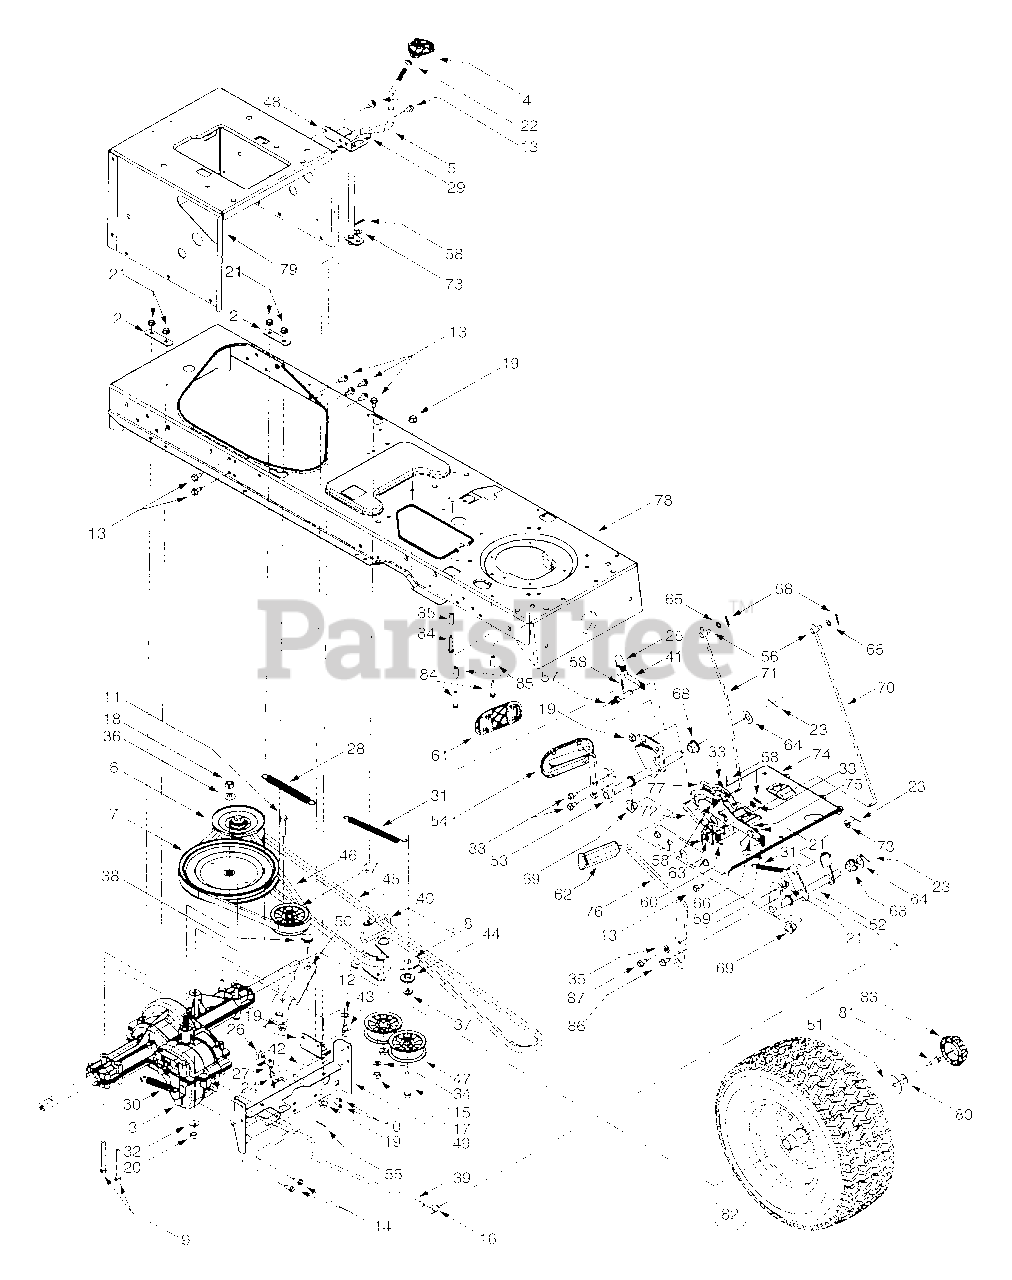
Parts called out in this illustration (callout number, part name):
3	Single-speed Transmission Assembly
4	Shifter Knob
5	Shift Lever
6	Variable-speed Pulley Assembly
7	Transmission Pulley, 8.5 x .5-36
8	Double-idler Bracket
9	Hex Cap Screw, 5/16-18 x 2.75
10	Self-tapping Screw, #8-18 x .5
11	Hex Cap Screw, 3/8-16 x 1.75
12	Flat Washer, .51 x 1.0 x .060
13	Self-tapping Screw, 5/16-18 x .625
14	Self-tapping Screw, 1/4-20 x .75
15	Hex Cap Screw, 3/8-16 x 2.25
16	Ferrule, 5/16-18
17	Hex Nut, 3/8-24
18	Hex Nut, 7/16-20
19	Flange Lock Nut, 3/8-16
20	Hex Nut, 3/8-16
21	Flange Lock Nut, 5/16-18
22	Jam Nut, 3/8-16
23	Cotter Pin
24	Internal Cotter Pin
25	Ball Joint
26	Short Spring Switch
27	Insulator Nut Plate
28	Extension Spring, .62 Dia. x 6.12
29	Compression Spring Clip
30	Extension Spring, .59 OD x 4
31	Extension Spring, .50 Dia. x 6.37
32	Bell Washer, .401 x .87 x .063
33	Flat Washer, .385 x .62 x .063
34	Lock Washer, 3/8
35	Flat Washer, .344 x .750 x .120
36	Bell Washer, .45 x 1.0 x .602
37	Flat Washer, .407 x .812 x .135
38	Shoulder Screw, .625 x .217
39	Brake Rod
40	Belt Guard
41	Idler Adjustment Rod, 3/8
42	Shift Rod
43	Adjustment Ferrule, 1/4-20 x 1.0
44	Shoulder Spacer, .38 ID
45	Lower Drive Belt
46	Upper Drive Belt
47	Flat Idler, 2.75 OD
48	Speed Control Rod Bracket
51	Flat Washer, .350 x 1.59 x .062
52	Brake Control Assembly
53	Speed Control Assembly
54	Drive Pedal Assembly
55	Cotter Pin, 1/8 x 1.25
56	Ferrule, 1/4-20
57	Pin, 3/8-16 x 2.43
58	Cotter Pin
59	Compression Spring, .34 OD x 1.0
60	Extension Spring, .50 OD x 1.41
61	Drive Pedal Pad
62	Brake Pedal Pad
63	Flat Washer, .281 x .5 x .063
64	Flat Washer, .64 x 1.24 x .06
65	Flat Washer, .344 x .062 x .03
66	Shoulder Screw, .437 x 1.62
67	Shoulder Screw, .5 x .434
68	Hex Flange Bearing
69	Split Hex Flange Bearing
70	Cruise Control Rod
71	Brake Lock Control Rod
72	Cruise Latch
73	Flat Washer, .344 x .688 x .065
75	Drive Lockout Bracket
81	Hex Cap Screw, 5/16-24 x .75
83	Hub Cap
84	Self-tapping Screw, 1/4-20 x 1.25
85	Spacer
86	Self-tapping Screw, 5/16-18 x .875
87	Self-tapping Screw, 5/16-18 x .75
88	Scr. TT 5/16-18
